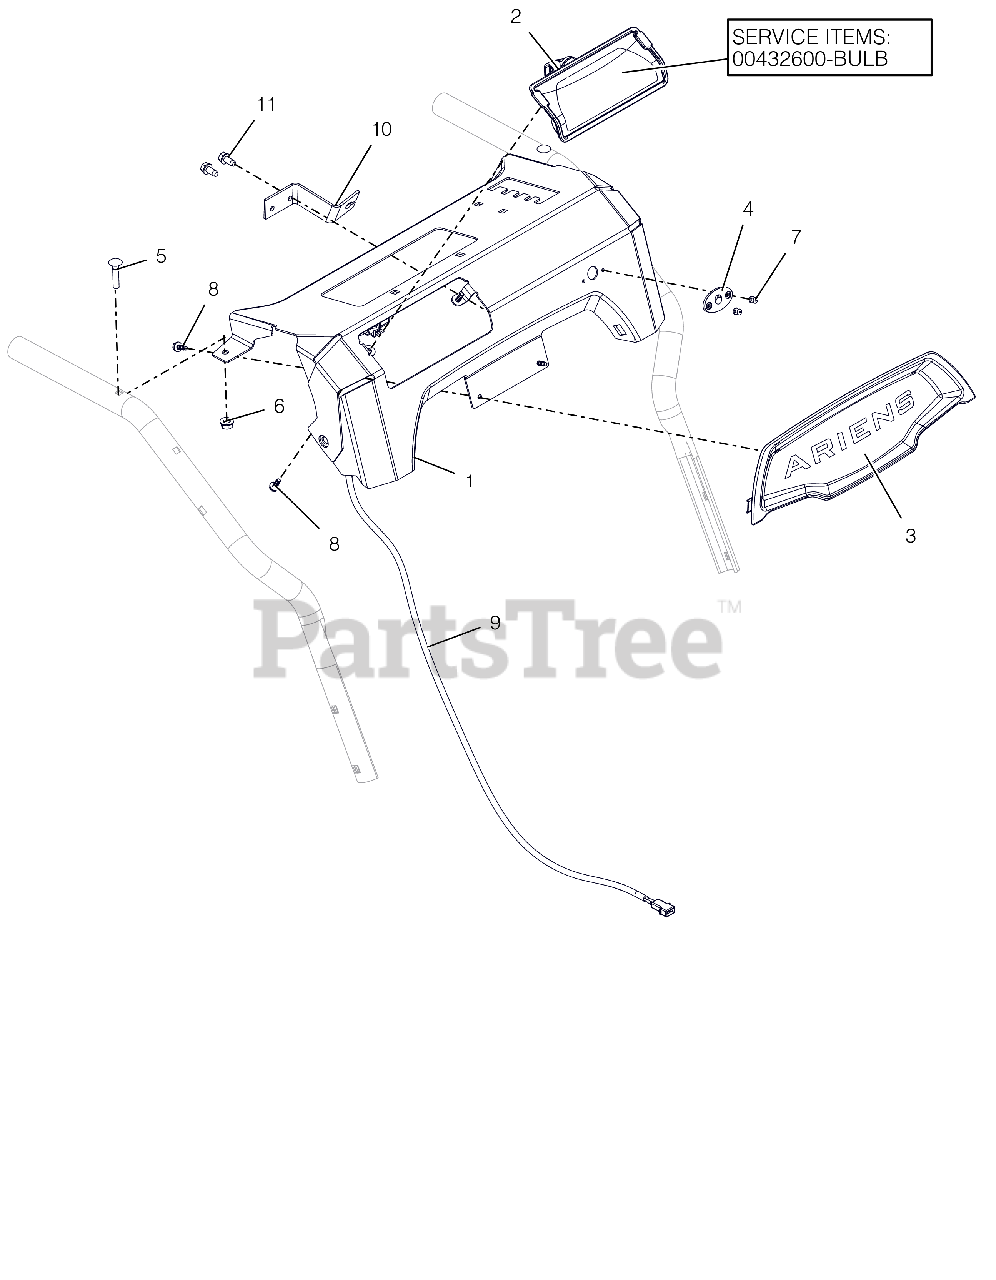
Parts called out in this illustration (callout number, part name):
1	CTRL PANEL W/DECAL-SM DASH DLX
2	HEADLIGHT ASY, HALO 20W 2SHOT
2	BULB, LIGHT-HALOGEN 20W
3	BEZEL, DASH - ARIENS SM DASH
4	BSHG, CHUTE CRANK
5	BLT-RDHDXLSQNK.25-20X1.25 G5ZC
6	@NUT-LK-TOP-FLG .25-20 YWZC
7	RVT-POP #43 .125X.313 STL ZINC
8	SCR-TAP #10X.50 BOSS INDHXHD
9	HARNESS, LIGHT - COMPACT
10	ANCHOR, DEFLECTOR CABLE
11	SCR-TAP .25-20X.50 HWH TR YWZ
